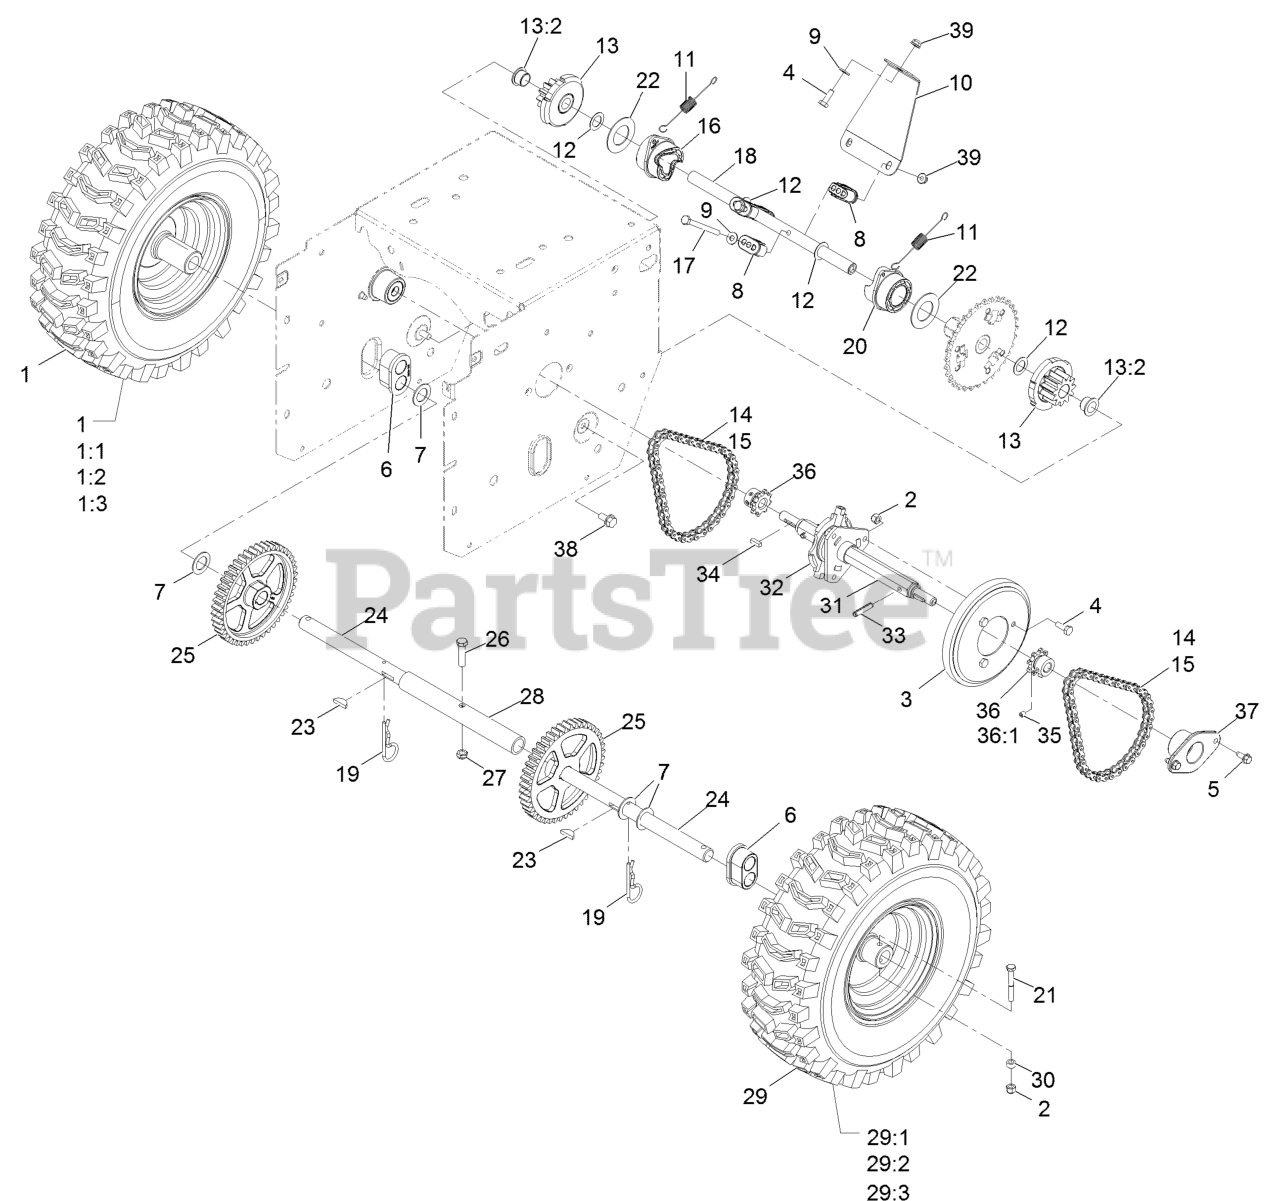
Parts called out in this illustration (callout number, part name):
1	RH Wheel And Tire ASM
1:2	Rim-Tire
1:3	Stem-Valve
2	Nut-Nyloc 1/4-20
3	Wheel-Friction
4	Screw-HH 1/4-20 X 3/4
5	Screw-HWH 1/4-20 X .62
6	Bearing-Axle
7	Washer-Thrust
8	Guide-Collar
9	Washer-1/4 SAE
10	Brace-Collar, Shift
11	Spring-Extension
12	Washer-Flat
13	11T Gear ASM
13:2	Bushing-Flange
14	Chain-Roller
15	Link-Connecting
16	Collar-Shift, RH
17	Screw-HH
18	Shaft-Intermediate
19	Pin-Hair
20	Collar-Shift, LH
21	Screw-HH
22	Washer-Thrust
23	Key-Woodruff
24	Shaft-Axle
25	Gear-Axle, 44 Tooth
26	Screw-HH 5/16-18 X 1 3/8
27	Nut-Nyloc 5/16-18 Thin
28	Tube-Axle
29	LH Wheel And Tire ASM
29:2	Rim-Tire
29:3	Stem-Valve
30	Spacer-Blade, Rotor
31	Shaft-Hex .
32	Trunnion-Hex
33	Pin-Roll, Slotted
34	Key-Square
35	Screw-HSH
36	Sprocket-8 Tooth
36:1	Screw-HSH
37	Retainer-Bearing
38	Screw-HWHTF
39	Nut-Nyloc 1/4-20 Flg
